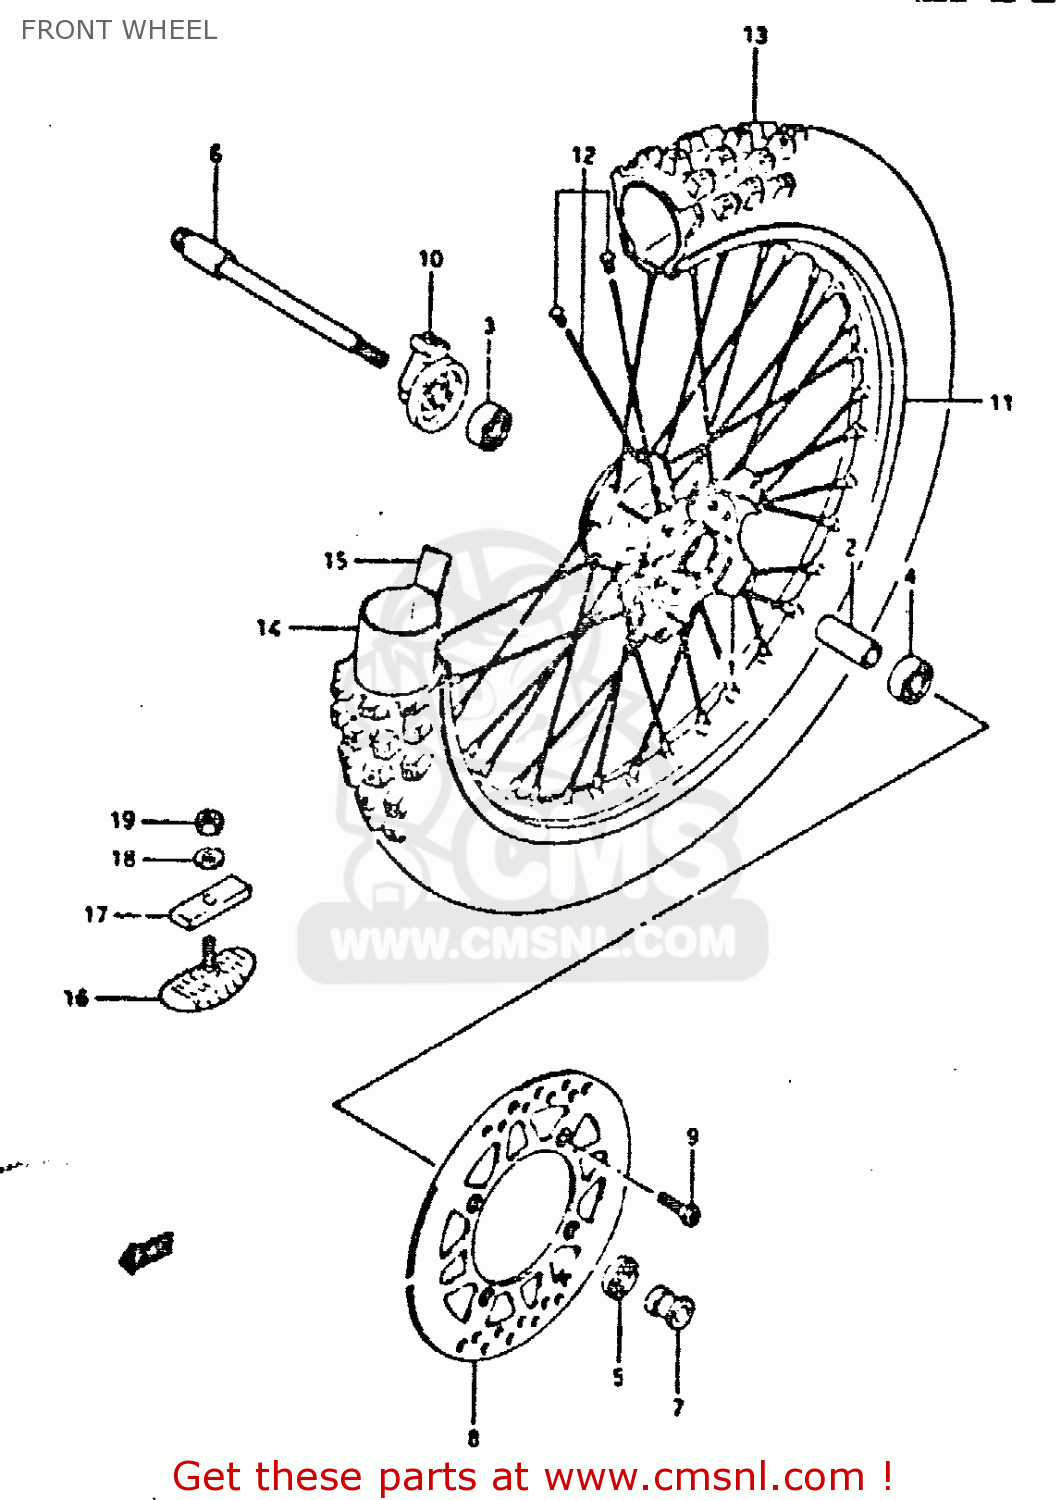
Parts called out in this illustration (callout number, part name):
1	HUB,FR WHEEL
2	SPACER,FR HUB BEARING
3	BEARING
4	BEARING
5	SEAL,OIL(22X35X5)
6	AXLE,FR
7	SPACER,FR AXLE,L
8	DISC,FR BRAKE
9	BOLT,BRAKE DISC
10	BOX ASSY,SPEEDOMETER GEAR
11	RIM,FRONT WHEEL (1.60X2
12	SPOKE SET,FR WHEEL
13	TIRE COMP,FRONT 80/100-21
14	TUBE
15	PROTECTOR,WHEEL INNER
16	STOPPER,BEAD
17	CUSHION,BEAD STOPPER
18	WASHER
19	NUT
